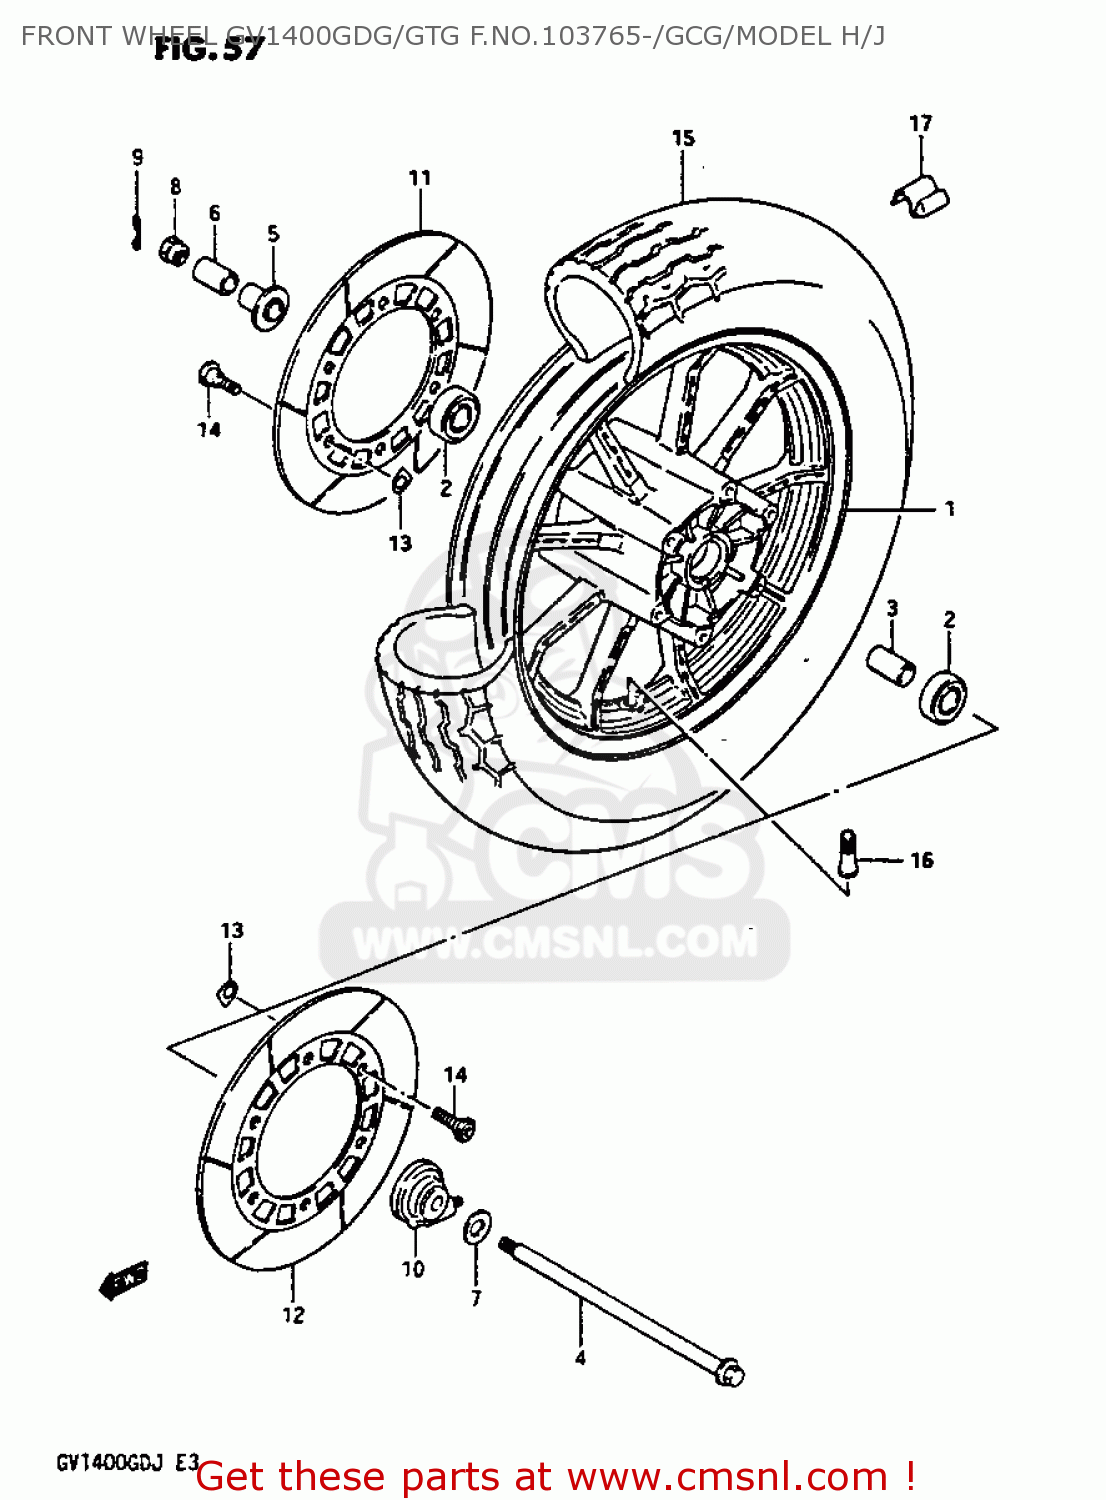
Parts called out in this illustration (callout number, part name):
1	WHEEL,FRONT (MT2.50X16)
2	BEARING
3	SPACER
4	AXLE,FRONT
5	SPACER,FR HUB BEARING,R
6	SPACER,FR AXLE,R
7	WASHER
8	NUT (12MM)
9	PIN,FRONT AXLE
10	BOX ASSY,SPEEDOMETER GEAR
11	DISC,FRONT BRAKE,RIGHT
12	DISC,FR BRAKE,L
13	SHIM,BRAKE DISC
14	BOLT(8X25.5)
15	TIRE,FRONT 130/90-16.6
16	VALVE,TIRE TR413 BS
17	BALANCER,WHEEL
